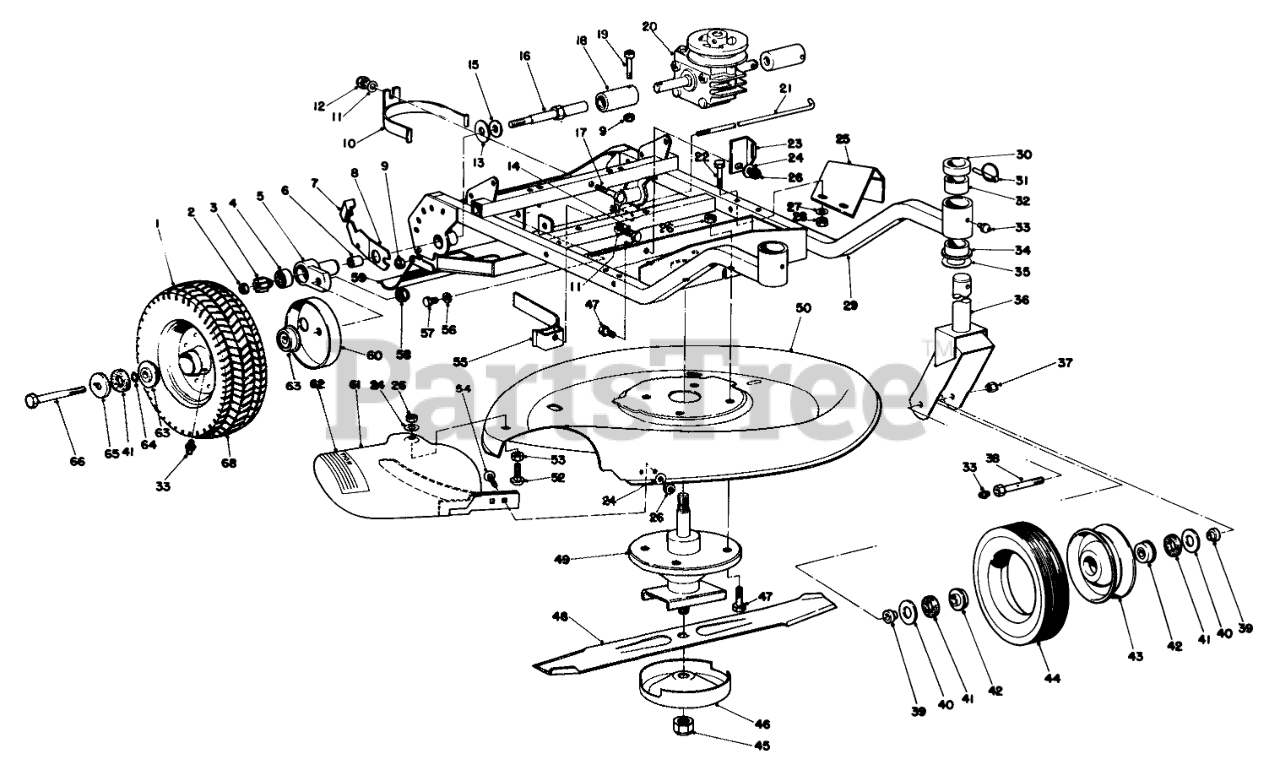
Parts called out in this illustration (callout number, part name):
1	Rear Wheel Assembly (Incl . Ref. #63)
2	NUT-HJ
3	Pinion Kit
4	.375 RPP BALL BEARING
5	Pivot Arm Assembly, Right (Incl. Ref. #4 & 6)
6	BUSHING
8	RH SPRING ARM ASM
9	NUT-LOCK, NI
10	Belt Retainer W.A.
11	WASHER-LOCK/SP
12	Locknut
13	Washer
14	SCREW-HH
15	Washer
16	DRIVE SPINDLE
17	SCREW-HH
18	CLUTCH ASM
19	DRIVE SCREW
20	Transmission Assembly
21	Safety Shield Rod
22	SCREW-HH
23	Belt Retainer
24	WASHER-PLAIN
25	Step Plate
26	Nut
27	WASHER-FLAT
28	NUT-LOCK
29	Frame (Incl. Ref #32 & 34)
30	HT OF CUT SPACER
31	PIN-LYNCH
32	7/8 ID X 1.128 X 7/8 LG BSHG
33	FITTING-GREASE
34	FLANGE BUSHING
35	WASHER
36	CASTOR FORK WA RO
37	NUT-HEX
38	AXLE BOLT
39	CASTOR SPACER
40	WASHER-FLAT
41	Washer
42	BEARING-BALL
43	Wheel (Incl. Ref.#42 & 44)
44	1.75-8 SEMIPNEU TIRE
46	Cup
47	SCREW-HH
48	Blade
49	Mower Spindle
50	25" DECK R
52	SCREW-CARR
53	PAL NUT
54	BOLT-CARR
55	Belt Retainer
56	WASHER-LOCK
57	SCREW-HH
58	NUT-LOCK, NI
59	Safety Shield
60	Wheel Cover
61	DefIector
62	Decal
63	BEARING
64	O-RING
65	SLINGER
66	SCREW-HH
68	3.50X10 SEMIPNEU TIRE
